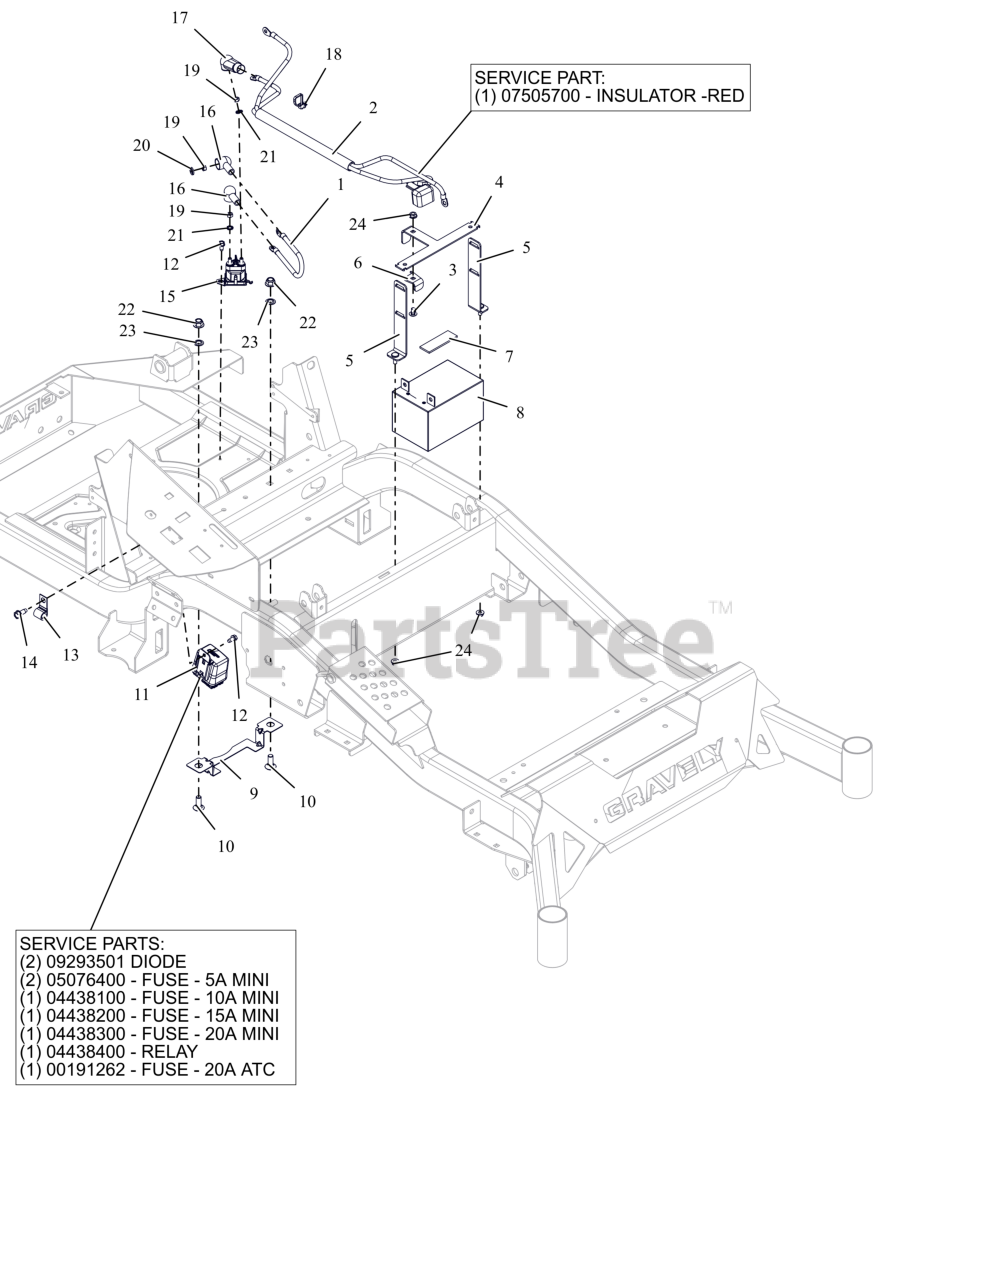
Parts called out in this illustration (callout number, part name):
1	CABLE, POS W/(2)1/4 RING 9.0LG
2	HARNESS, BATTERY HD
2	INSULATOR
3	BLT, RHSN .25-20X.500 G5 ZCC
4	BRKT, BATTERY TIE DOWN
5	WMT,BATTERY MOUNT HOLD DOWN
6	BRKT, BATTERY HOLD
7	PAD,RBR 1.0"X3.0" W/ADHESIVE
8	BATTERY, 12V 12A -190CCA
9	GUARD, ELECTRICAL HARNESS
10	BLT, RHSN .38-16X1.00 G5 ZCC
11	HARNESS, WIRE
11	DIODE, CONNECTOR SHELL
11	FUSE, 5 AMP MINI-ATC
11	FUSE,10 AMP MINI-ATC
11	FUSE,15 AMP MINI-ATC
11	FUSE,20 AMP MINI ATC
11	RELAY,MICRO5 TERML W/RESISTOR
11	FUSE, 20 AMP BLADE S/O
12	SCR-TAP .25-20X.50 HWH ZCC
14	SCR,TAP .312-18X.75 HWH TR ZCC
15	SOLENOID, STARTER (SEALED)
16	BOOT, EYELET TERMINAL
17	BOOT, .65ID POS
18	CABLE TIE W/ TREE (.25 HOLE)
19	NUT-STD M6-1.0 ZCC
20	WSHR,LK-REG .312X.078 ZCC
21	WSHR,LK-EXT.262X.502X.026 ZCC
22	NUT,NYL-FLG .38-16 GF ZCC
23	NUT-PUSH .38 DIA. PAL ZINC
24	NUT-LK-TOP-FLG .250-20 GF ZCC
